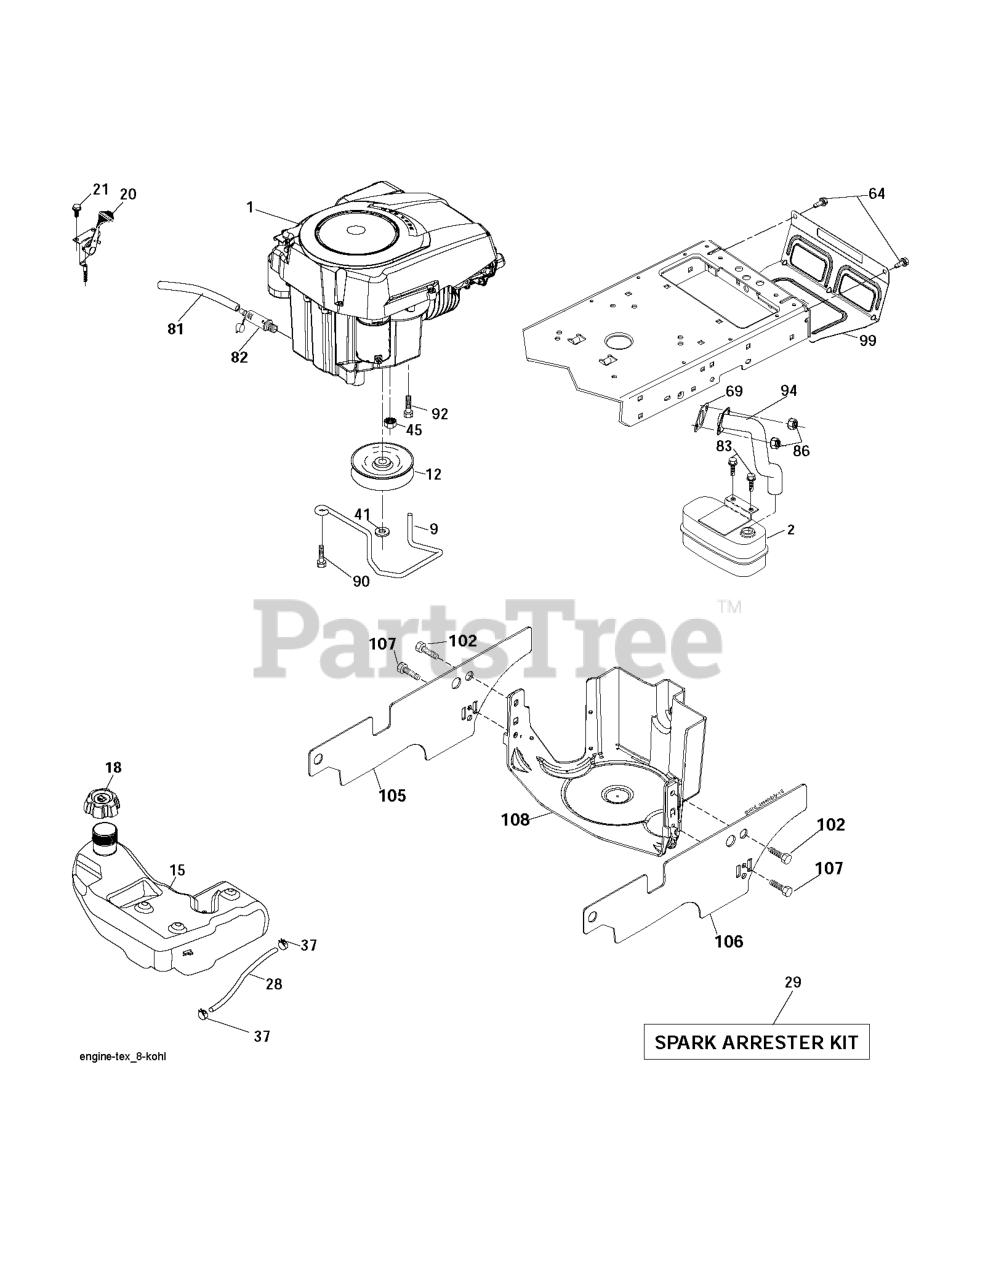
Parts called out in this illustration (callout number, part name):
2	MUFFLER.SINGLE.CYL.KOHL/B&S
9	KEEPER.BELT.ENGINE.3.25 (3 2)
12	PULLEY ENGINE
15	RP TANK FUEL FRT 1.5 GAL
18	FUEL CAP
20	CONTROL.TH/CK.C.
21	SCREW
28	LINE.FUEL.20
29	KIT.SPARK ARRESTOR 794945 B&S
37	HOSE CLAMP
42	LOCKWASHER
43	BOLT HEX 7/16-20X4-1/4"
45	NUT
81	TUBE, DRAIN OIL ASM.
82	PLUG DRAIN OIL EASY
83	BOLT.5/16-18UNCX3/4 W/SEMS.BLK
90	SCREW 3/8-16X1
92	SCREW 3/8-16X1
94	RP.TUBE.EXHAUST.KOHL.COURAGE
95	SCREW.SOCKET HD.5/16-1
97	SCREW HEXWSHR 1/4-20X3/4
102	SCREW
105	SHIELD.SIDE.LH.3842"TEX FRENCH
106	SHIELD.SIDE.RH.3842"TEX FRENCH
107	SCREW.1/4-20X5/8
